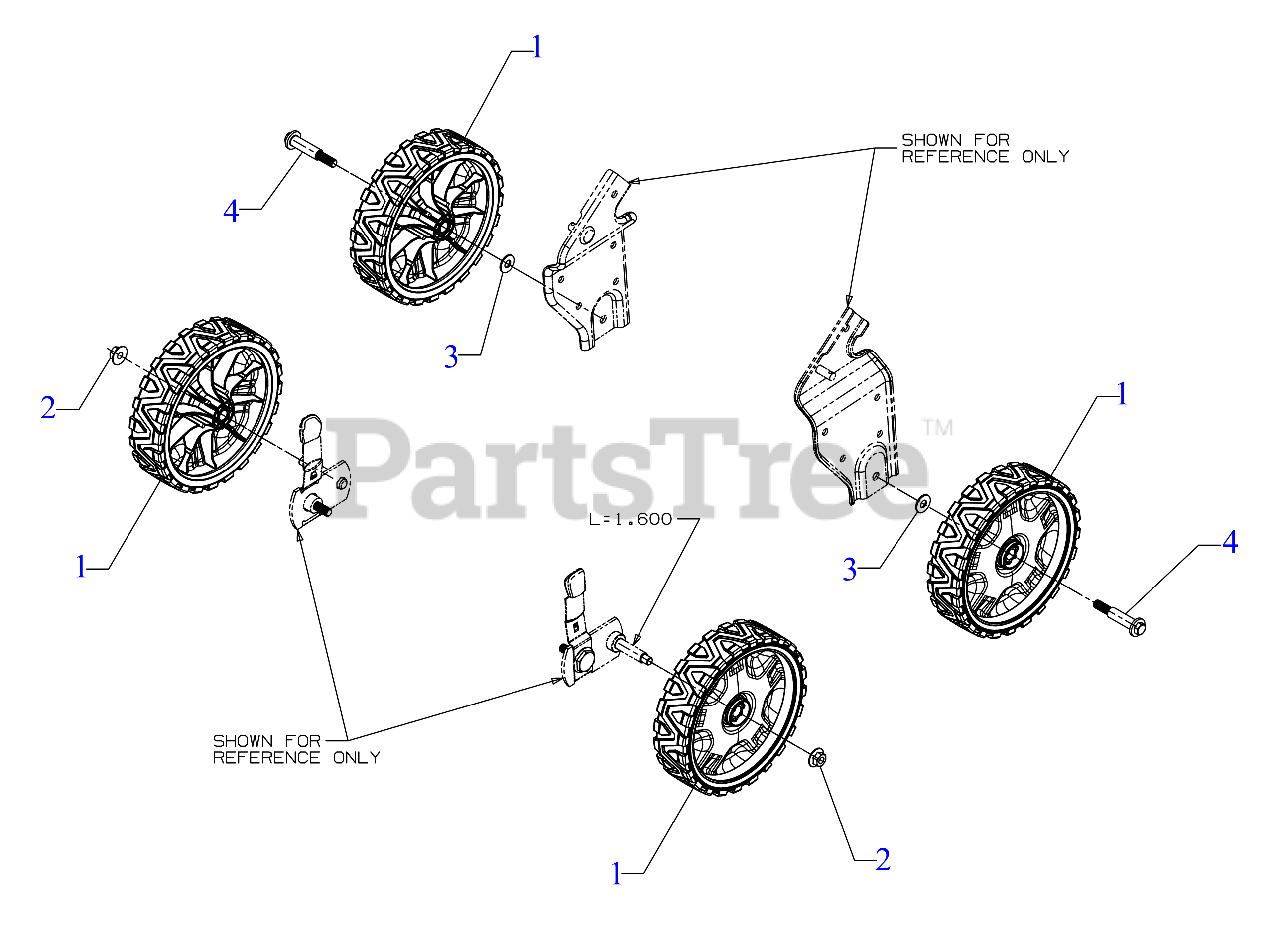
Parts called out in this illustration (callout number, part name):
1	WHEEL ASSEMBLY (8 x 2)
2	FLANGE LOCK NUT
3	BELL WASHER .400 ID x .88 x .060
4	SHOULDER SCREW .496X1.605 3/8-16
